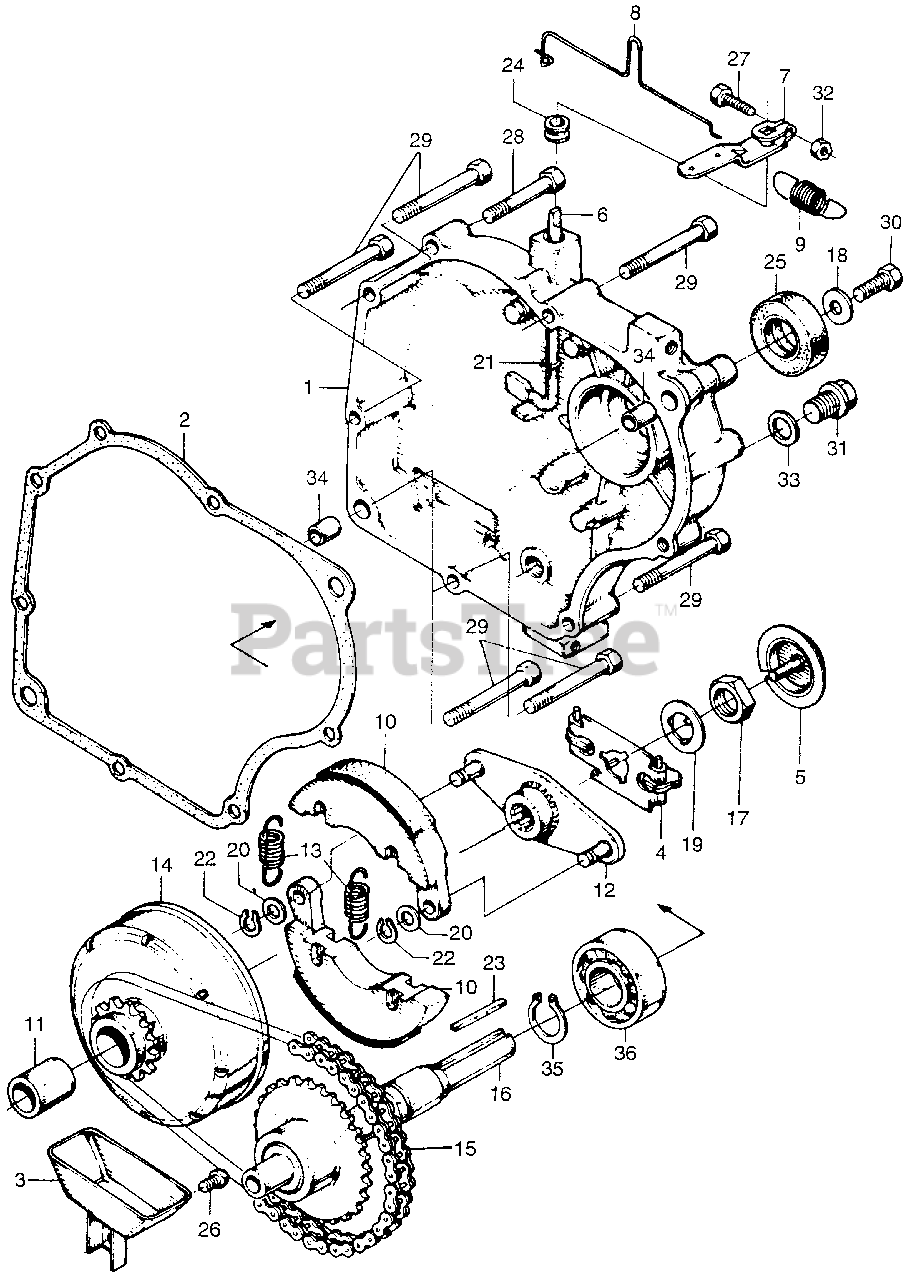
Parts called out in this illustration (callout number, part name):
1	COVER, R. CRANKCASE
1	COVER, R. CRANKCASE (NOT AVAILABLE)
2	GASKET, CASE (NOT AVAILABLE)
3	SEPARATOR, CLUTCH
4	HOLDER, GOVERNOR WEIGHT (NOT AVAILABLE)
5	SLIDER, GOVERNOR
6	SHAFT, ARM (NOT AVAILABLE)
7	ARM, GOVERNOR (NOT AVAILABLE)
8	ROD, GOVERNOR (NOT AVAILABLE)
9	SPRING, GOVERNOR (NOT AVAILABLE)
10	WEIGHT, CLUTCH (NOT AVAILABLE)
11	GUIDE, CLUTCH CENTER
12	PLATE, DRIVE (NOT AVAILABLE)
13	SPRING, CLUTCH (NOT AVAILABLE)
14	SPROCKET, DRIVE
15	CHAIN A, DRIVE
16	SHAFT D, P.T.O. (NOT AVAILABLE)
17	NUT, LOCK (14MM)
18	WASHER (8MM)
19	WASHER, LOCK (14MM)
20	WASHER (8MM) (NOT AVAILABLE)
21	CIRCLIP (5MM) (NOT AVAILABLE)
22	CIRCLIP (OUTER) (8MM)
23	KEY (5X5X33)
25	OIL SEAL (25X40X7)
26	BOLT, HEX. (5X8)
27	BOLT, HEX. (5X14)
28	BOLT, HEX. (6X32)
29	BOLT, HEX. (6X45)
30	BOLT, HEX. (8X20)
31	BOLT, DRAIN PLUG (12MM)
32	NUT, HEX. (5MM)
33	WASHER, DRAIN PLUG (12MM)
34	PIN A, DOWEL (10X16)
35	CIRCLIP (OUTER) (25MM)
36	BEARING, RADIAL BALL (6004)
